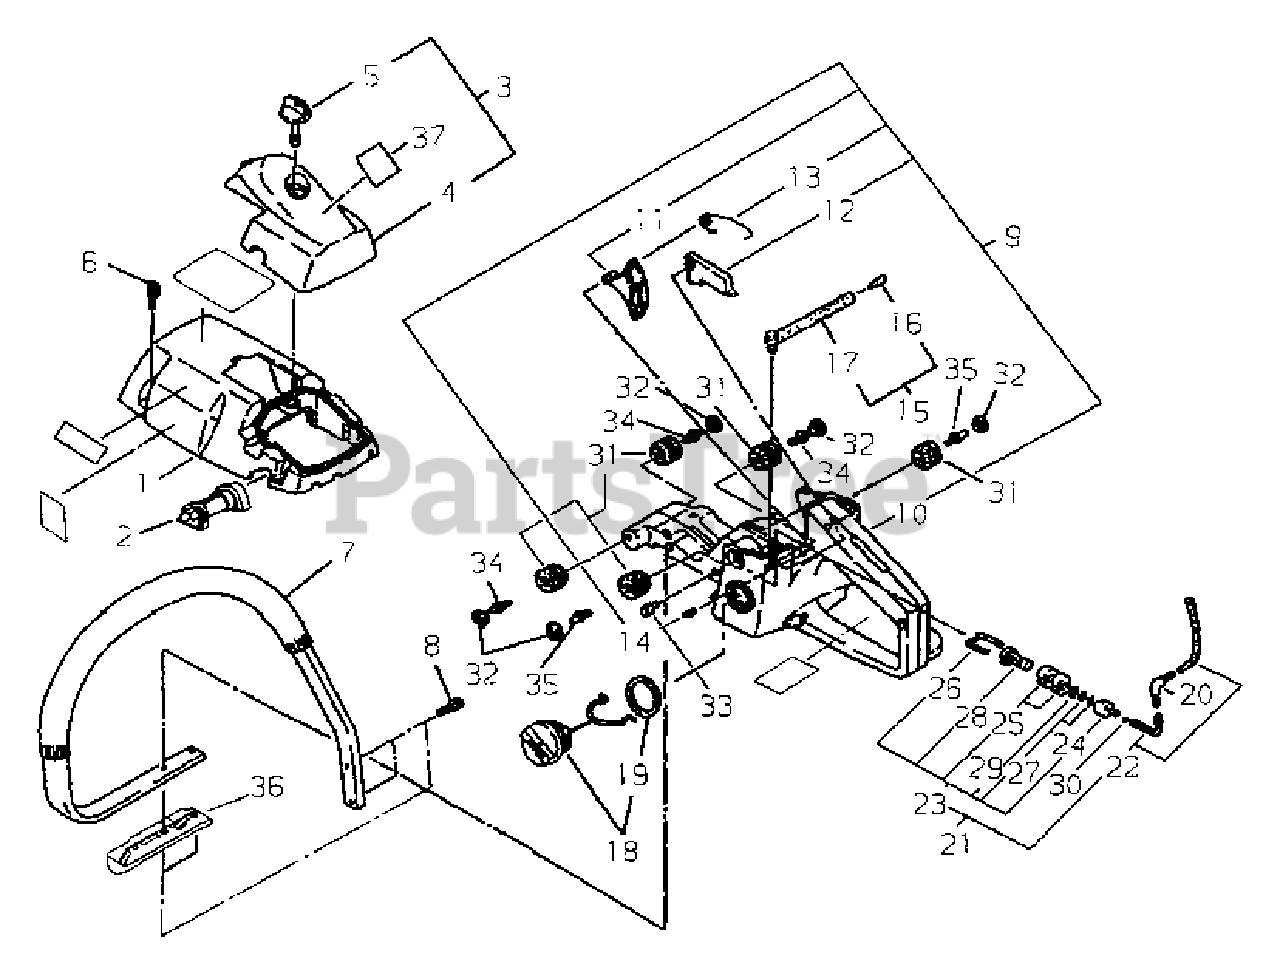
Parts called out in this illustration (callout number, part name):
1	COVER, ENGINE
3	AIR FILTER COVER ASSY
4	COVER, AIR FILTER
5	THUMBSCREW
6	BOLT, ADHESIVE M4×16
7	HANDLE, FRONT
8	BOLT - TAPPING
9	REAR HANDLE SUB ASSY
10	HANDLE, REAR
11	TRIGGER, THROTTLE
12	LEVER, LOCK
13	SPRING, TORSION
14	PIN 4×25
15	VENT ASSY
16	VENT ASSY
17	PIPE, FUEL VENT
18	CAP ASSY
19	GASKET, CAP
20	CONNECTOR
21	PIPE ASSY, FUEL
22	PIPE, FUEL
23	FILTER, FUEL
24	WEIGHT, FUEL LINE
25	FILTER, FUEL
26	CLIP, FILTER
27	SCREEN, FILTER
28	BODY, FUEL FILTER
29	RING, RETAINING
30	CLIP Ø6
31	CUSHION
32	CAP, CUSHION
33	SUPPORT
34	BOLT M5
35	BOLT M5
37	LABEL - INSTRUCTION
